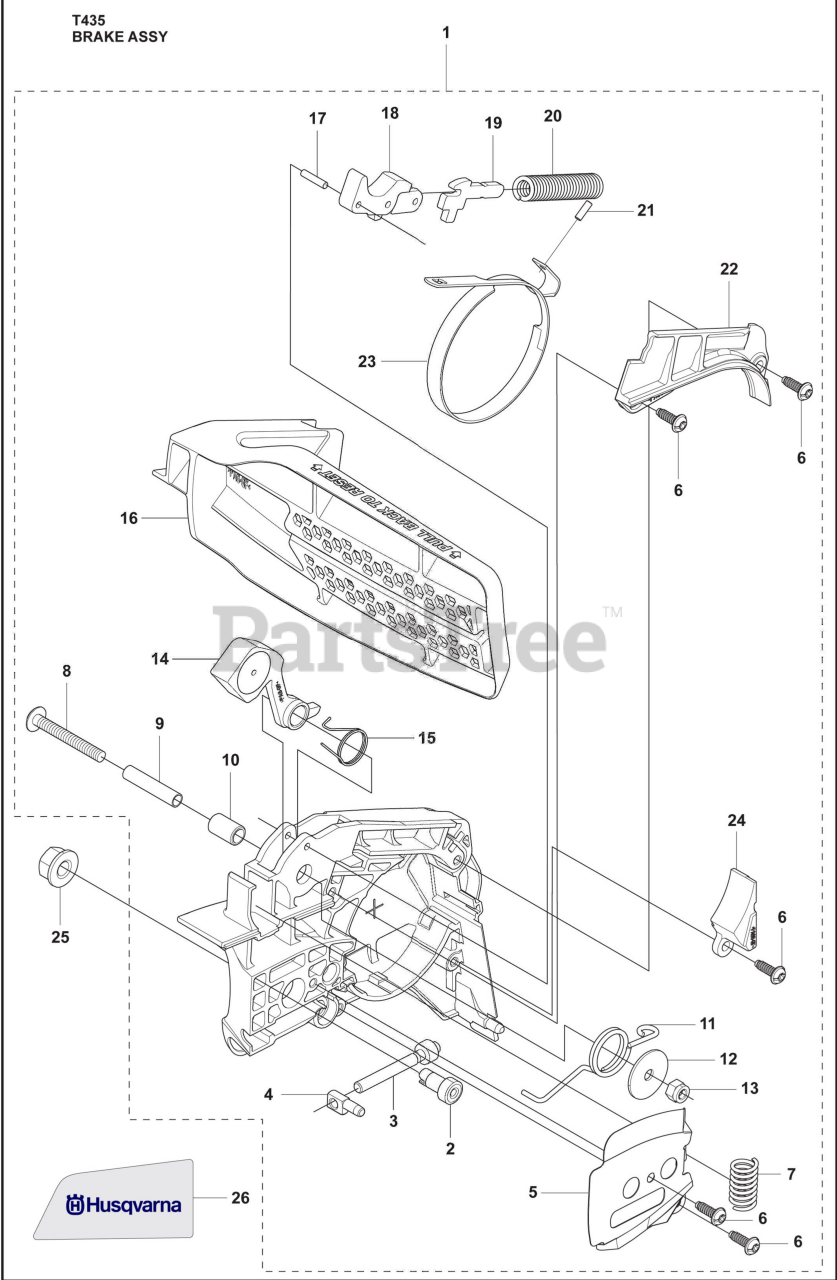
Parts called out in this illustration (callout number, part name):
1	Brake assy
2	Gear
3	Screw
4	Tension knob
6	Screw
8	Bolt
9	Spacer
10	Spacer
11	Spring
12	Washer
13	Nut
15	Spring
16	Hand guard
17	Pin
19	Arm
20	Spring
21	Pin
22	Brake cover
23	Brake band
26	Decal, clutch cover
